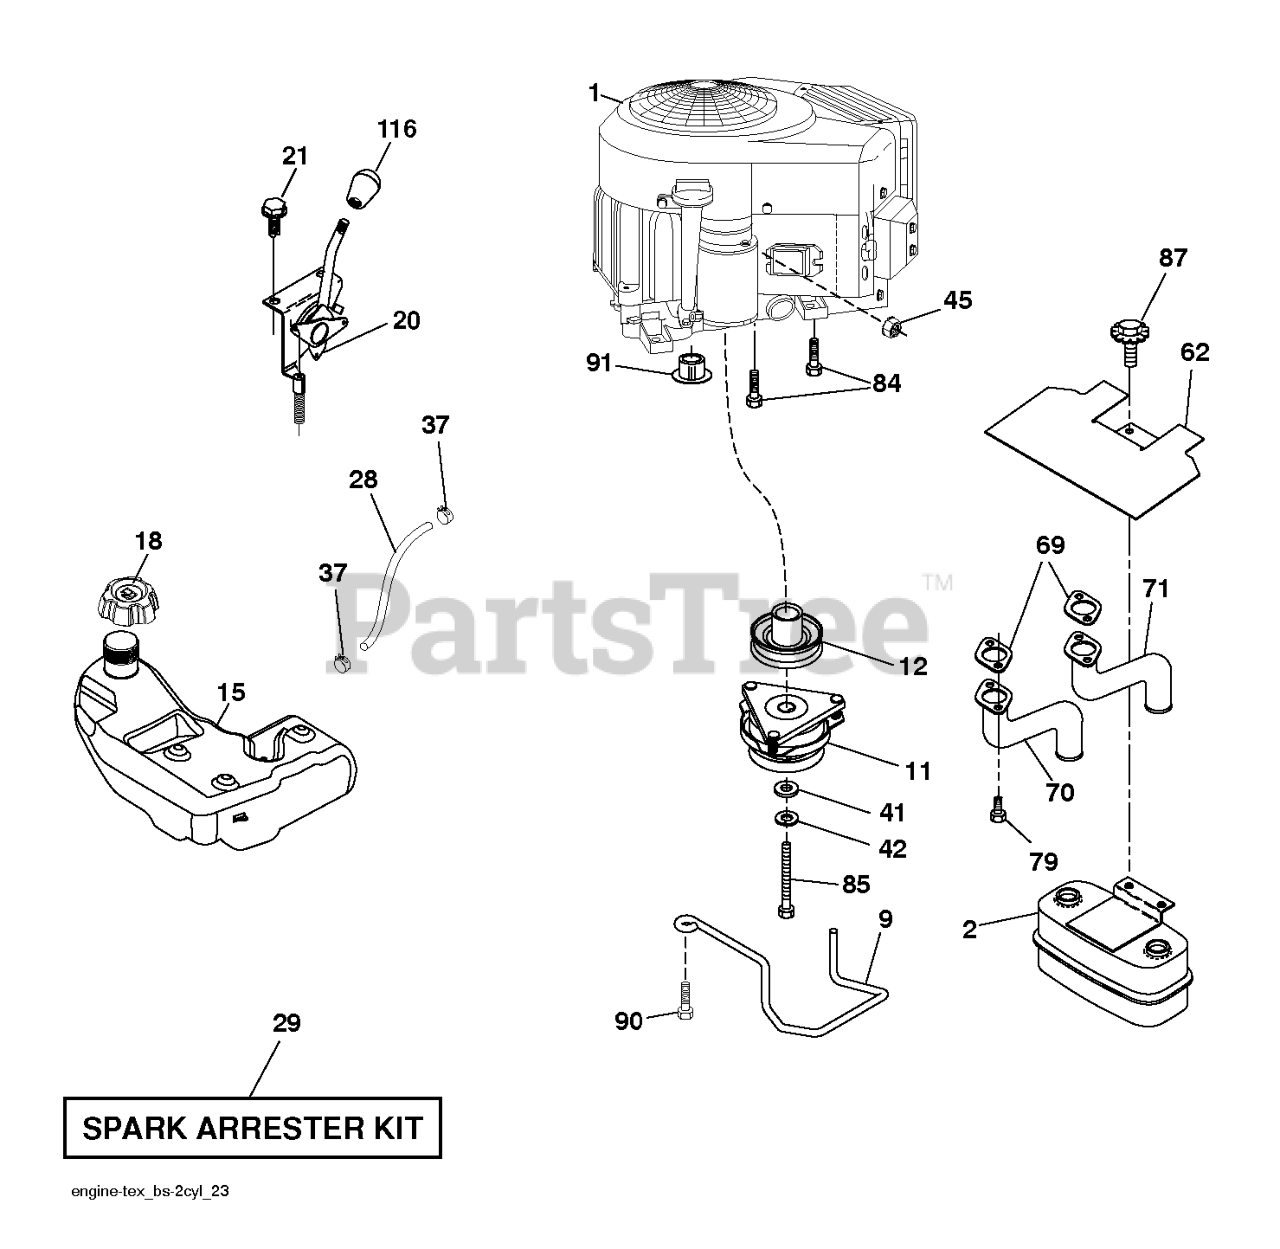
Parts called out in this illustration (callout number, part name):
2	MUFFLER.TWIN.CYL.LOW.TONE
9	KEEPER.BELT.ENGINE.4.2
11	CLUTCH.ELECTRIC.LT.48"*
12	PULLEY.ENGINE.TUFFTORQ
15	RP_TANK.ASSY.3.GAL.EPA
18	CAP.ASM.FL.RITCH.3"E10.SYM.498
20	CONTROL THROTTLE/CHOKE
21	SCREW.#10 X 0.750.BOS
28	LINE.FUEL.64"REAR.EMIS
29	KIT.SPARK ARRESTOR 794945 B&S
37	HOSE CLAMP
42	LOCKWASHER
45	NUT
62	SHIELD.HEAT.MUFFLER
69	GASKET.MUFFLER
70	EXHAUST.TUBE.LH.BS/TWIN
71	EXHAUST.TUBE.RH.B&S.TWIN.INTEK
79	SCREW.SOCKET.HEAD.5/16-18
84	SCREW.3/8-16
85	BOLT HEX 7/16-20X4-1/4"
87	BOLT 5/1618UNC X 3/4 W/ SEMS
90	SCREW 3/8-16X1
91	BUSHING.1.375OD
116	KNOB - SHIFT
